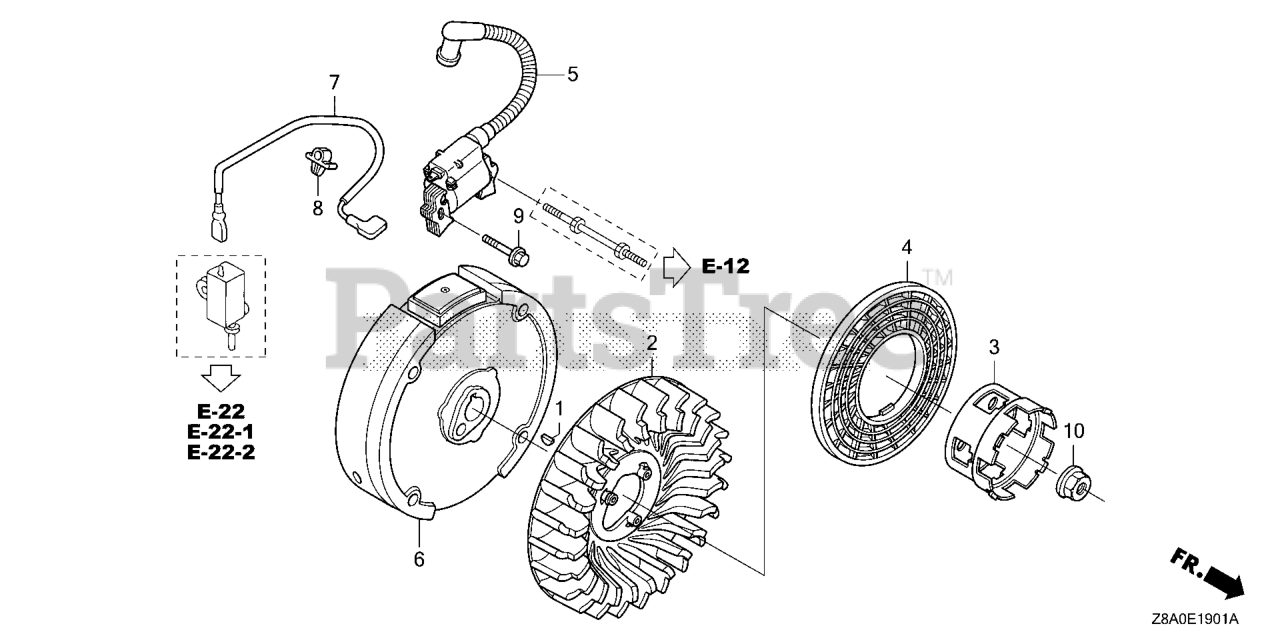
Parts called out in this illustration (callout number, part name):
1	KEY, SPECIAL WOODRUFF (25X18)
2	FAN, COOLING
3	PULLEY, STARTER
5	COIL ASSY., IGNITION (PHELON)
6	FLYWHEEL
7	WIRE, STOP SWITCH
8	CLIP, CABLE (A)
9	BOLT, FLANGE (6X23)
10	NUT, SPECIAL (14MM)
